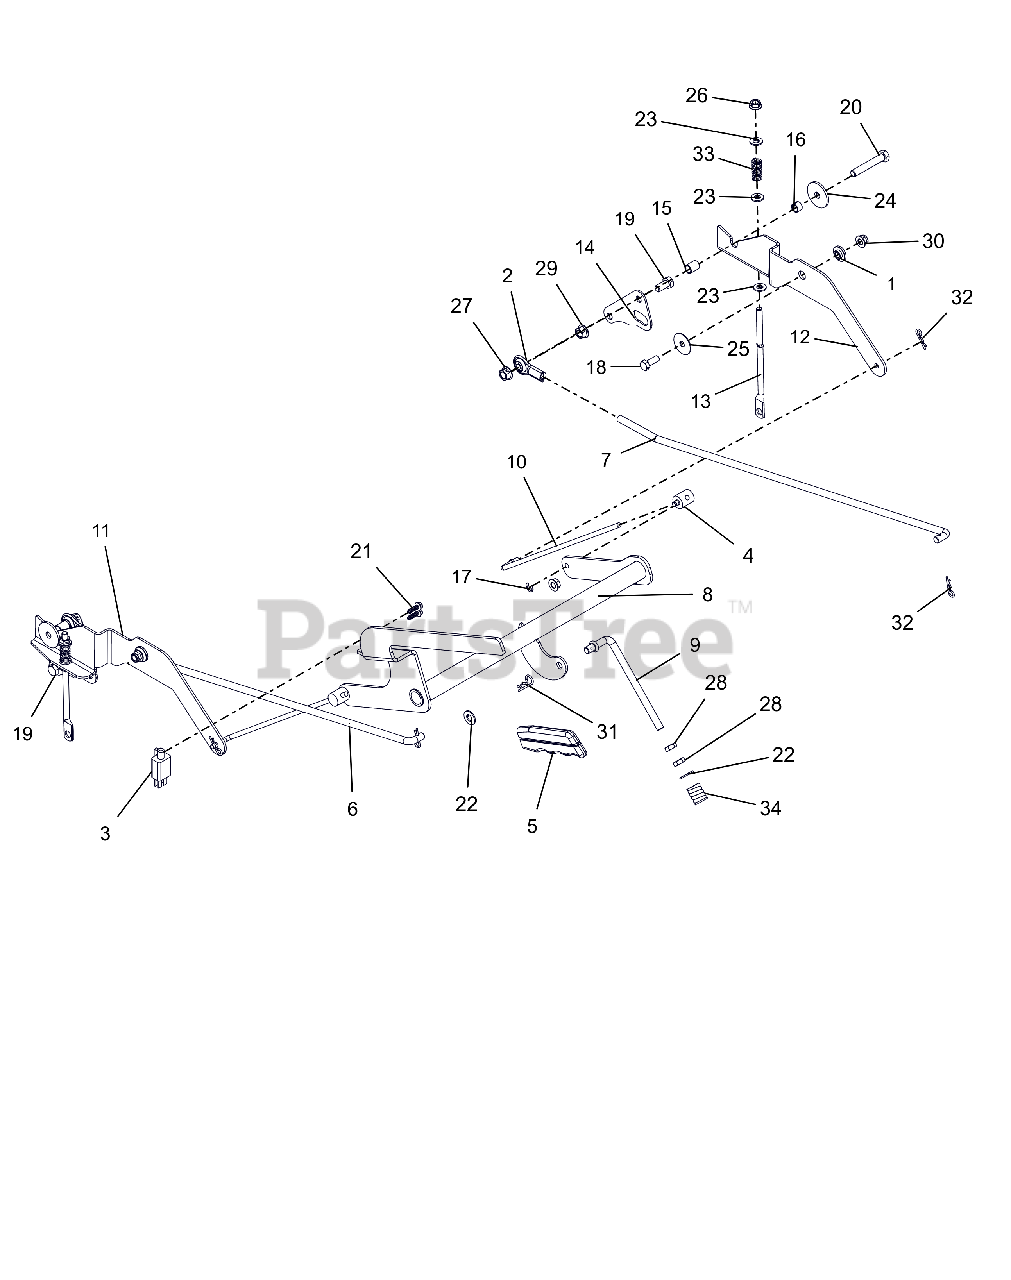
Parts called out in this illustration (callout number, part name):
1	BSHG, FLG .325X.499X.26X.88
2	ROD END, .38 RH
3	SWITCH- DOUBLE POLE N.O./N.O.
4	TRUNION, 1/4-20
5	GRIP, PARKING BRAKE (YELLOW)
6	STEERING, LINKAGE RH
7	STEERING, LINKAGE LH
8	WLDMT, BRAKE LEVER
9	LINK, OVER CENTER, PARKING BRK
10	LINK, BRAKE ARM
11	INTERLOCK, RH BRAKE LINK
12	INTERLOCK, LH BRAKE LINK
13	LINK, BRAKE COG
14	PLATE, TRANSAXLE ADAPTOR
15	SPCR, SLV .385X.500X.652
16	SPCR, SLV .385X.500X.350
17	RG-RTNG-EXT .250X.025
18	BOLT-HEX.31-18X.875 YWZC GR5
19	@BLT-HEX .38-16X.75 GR5 YWZC
20	@BLT-HEX .38-16X2.25 GR5 YWZC
21	SCR-TAP #12X.75 BOSS INDHXHD
22	@WSHR-FL-STL.406X.812X.065 YWZ
23	@WSHR-FL-STL.344X.688X.065YWZC
24	WSHR-FL-STL .380X1.50X.125YWZC
25	WSHR-FL-STL .347X1.254X.048YWZ
26	@NUT-LK-CTR-FLG .31-18 YZ GR F
27	NUT-LK-CTR-FLG .38-16 YWZC
28	NUT-HEX-JAM .375-16 YWZC
29	@NUT-LK-TOP-FLG .38-16 YWZC
30	@NUT-LK-NYL-FLG .31-18 YWZC
31	PIN-HAIR CTR .09 X 1.50 YWZC
32	PIN-HAIR INT .08X.18X1.18 YWZC
33	SPRING, COMPRESSION
34	SG-COMP .187X.56X1.62
